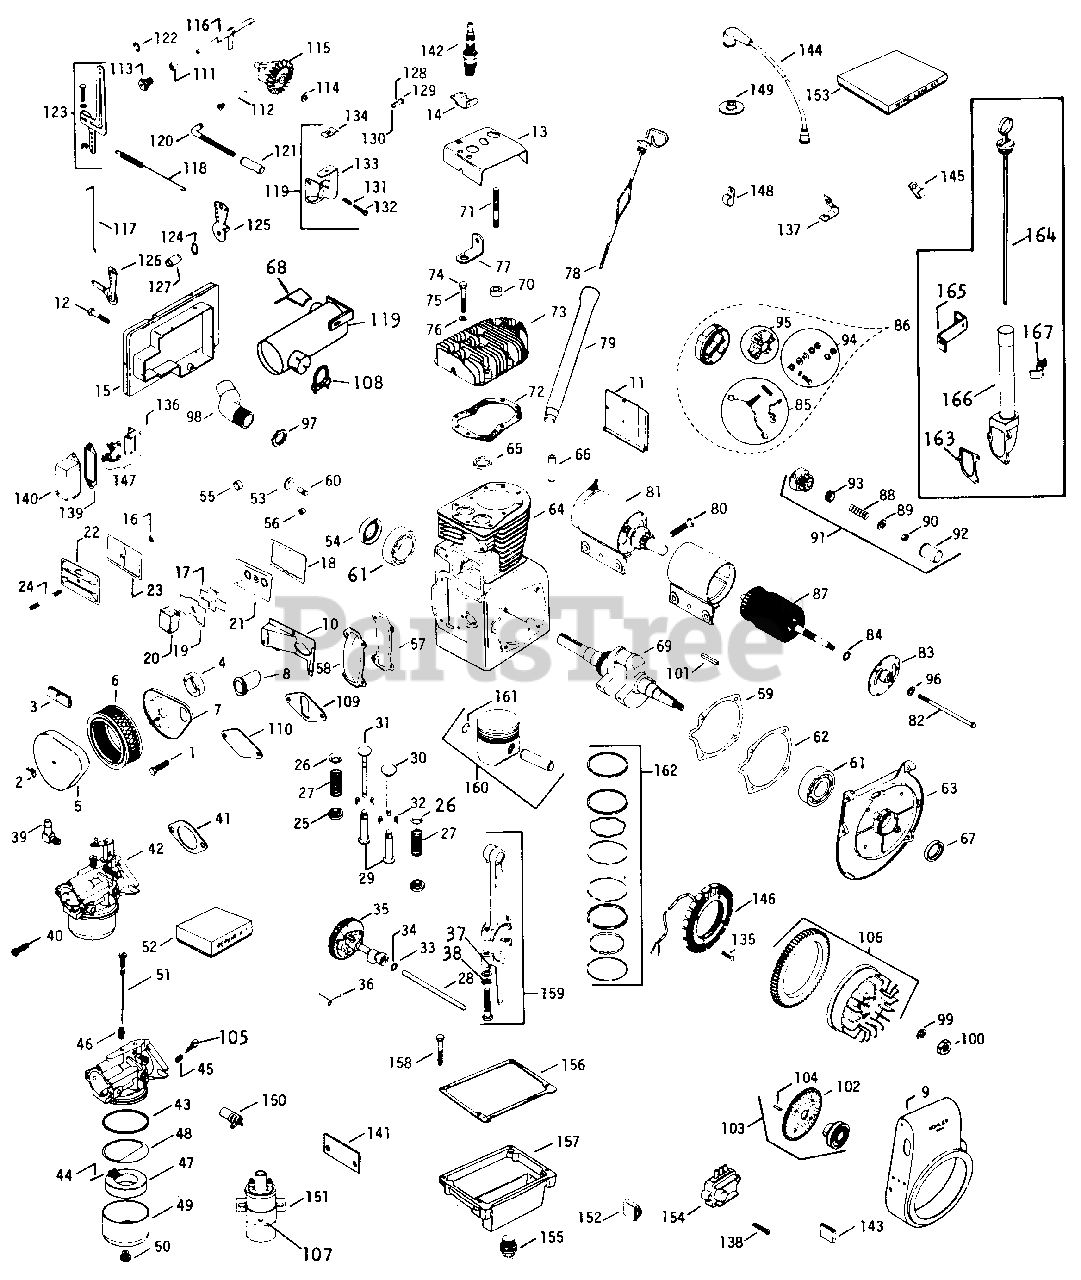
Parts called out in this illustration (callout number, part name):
1	Screw, 10-32 X 1/2 Znd Hex Hd Self Tap
2	Nut, Wing
4	Gasket, Air Cleaner
5	Cover, Air Cleaner
6	Element, Air Cleaner
7	Base, Air Cleaner
8	Tube, Air Cleaner
9	Housing, Blower
10	Baffle, Side
11	Baffle, Cylinder
12	Screw, 1/4-20 X 3/4 Hex Hd
13	Baffle, Head
14	Bracket, Lifting
16	Seal, Breather
17	Reed, Breather
18	Gasket, Cover
19	Baffle, Breather
20	Filter, Breather
21	Plate, Breather
22	Cover, Breather
23	Gasket, Valve Cover
24	Stud, Valve Cover
25	Retainer, Valve Spring
26	Retainer,Valve Spring
27	Spring, Valve
28	Pin, Camshaft
29	Tappet Assy
30	Valve, Intake
31	Valve, Exhaust
32	Keeper, Valve Spring
33	Shim, Camshaft, .005
34	Shim, Camshaft, .010
35	Camshaft Assy
36	Spring, Camshaft Actuating
37	Washer, Connecting Rod
38	Washer, 3/8 Heavy Lock
39	Elbow, Hose Connector
40	Screw, 5/16-18 X 1 Hex Hd Sems
41	Gasket, Carburetor
42	Carburetor Assy
43	Gasket, Fuel Bowl
44	Pin, Hinge
45	Spring, Idle Adjusting Screw
46	Spring, High Speed Needle
47	Float & Lever Assy
48	Gasket, Bowl Baffle
49	Bowl, Fuel
50	Screw w/Gasket, Fuel Bowl
51	Needle, High Speed
52	Kit, Carburetor Repair
53	Plug, 1-1/8 Expansion
54	Seal, Rear Oil
55	Plug, 1/2 Cup
56	Bearing, Crankcase Needle
57	Gasket, Cam Cover
58	Cover, Cam
59	Gasket, Bearing Plate, .010
60	Shaft, Governor
61	Bearing, Crankcase Ball
62	Gasket, Bearing Plate
63	Plate, Bearing
64	Block, Cylinder
65	Insert, Exhaust Valve
66	Guide, Valve
67	Seal, Front Oil
68	Deflector, Exhaust
70	Spacer
71	Stud, Cylinder Head
72	Gasket, Cylinder Head
73	Head, Cylinder
74	Screw, 3/8-16 X 1-1/2 Znd Hex Hd Cap Type 8
75	Screw, 3/8-16 X 1-3/4 Znd Hex Hd Cap Type 8
76	Washer, Head
77	Bracket, Baffle Mounting
78	Dipstick w/Shoulder Mount
79	Tube, Oil Fill w/Shoulder Mount
80	Bolt, Shoulder
81	Starter Assy
83	Cap Assy, Drive End
84	Washer, Armature Thrust
85	Kit, Starter Brush
86	Cap Assy, Commutator End
88	Spring, Anti-Drift
89	Spacer, Stop Gear
90	Nut, 5/16-24 Hex Lock
91	Kit, Starter Drive w/Shim
92	Cover, Dust
93	Spacer
94	Kit, Hardware
95	Kit, Brush Holder
96	Washer, 1/4 Znd Reg Lock
97	Nut, Lock
98	Elbow, Exhaust
100	Nut, 5/8-18 Znd Hex Lock
101	Key, 3/16 X 1-3/8 Sq Parallel
102	Screen, Grass
103	Cup Assy, Flywheel Drive
104	Pin, Flywheel Drive Cup
105	Screw, Idle Adjusting
106	Flywheel Assy
107	Clamp, Ignition Coil
108	Clamp Assy, Muffler
109	Gasket, Pump Cover
110	Cover, Pad
111	Spacer
112	Pin, Governor Stop
113	Bushing, Governor
114	Washer, Thrust
115	Gear, Governor
116	Shaft, Governor
117	Linkage, Choke
118	Spring, Governor
119	Muffler Assy
120	Rod, Ball Joint
121	Body, Ball Joint
122	Retainer, Throttle Rod
123	Lever, Governor
124	Washer, Tension
125	Lever, Throttle Control
126	Lever, Choke Control
128	Clamp, Swivel Wire
129	Washer, 9/32 X 5/8 X .062 Znd
130	Screw, 1/4-20 X 1-1/4 Hex Hd Sems
131	Spring, Adjusting
132	Screw, Throttle
133	Bracket, Control
134	Clamp, Wire
135	Screw, 10-24 X 3/8 Fil Hd Mach
136	Rod, Breaker
137	Clip, High Tension
138	Screw, 10-24 X 1 Znd Pan Hd Mach
139	Gasket, Breaker Cover
140	Cover, Breaker
141	Bar, Coil Bracket Back Plate
142	Plug, Spark (Champion)
143	Connector
144	Kit, Hi-Tension Lead
145	Clip, Terminal
146	Kit, Stator
147	Breaker & Bracket Assy
148	Clip, Cable
149	Grommet, Spark Plug
150	Condenser, Ignition Coil
151	Coil, Ignition
153	Kit, Wire Lead Cable
154	Regulator Assy
155	Plug, Drain
156	Gasket, Oil Pan Base
157	Base, Oil Pan
158	Screw w/Lock Washer, 3/8-16 X 1-1/2 Znd Hex Hd
159	Rod Assy, Connecting, Std
160	Piston Assy, Std
161	Retainer, Piston Pin
162	Ring Set, Piston, Std
163	Gasket, Oil Fill Tube
164	Dipstick w/o Shoulder Mount
165	Bracket, Dipstick Tube
166	Tube Assy, Oil Fill w/o Shoulder Mount
167	Clamp, Conduit
